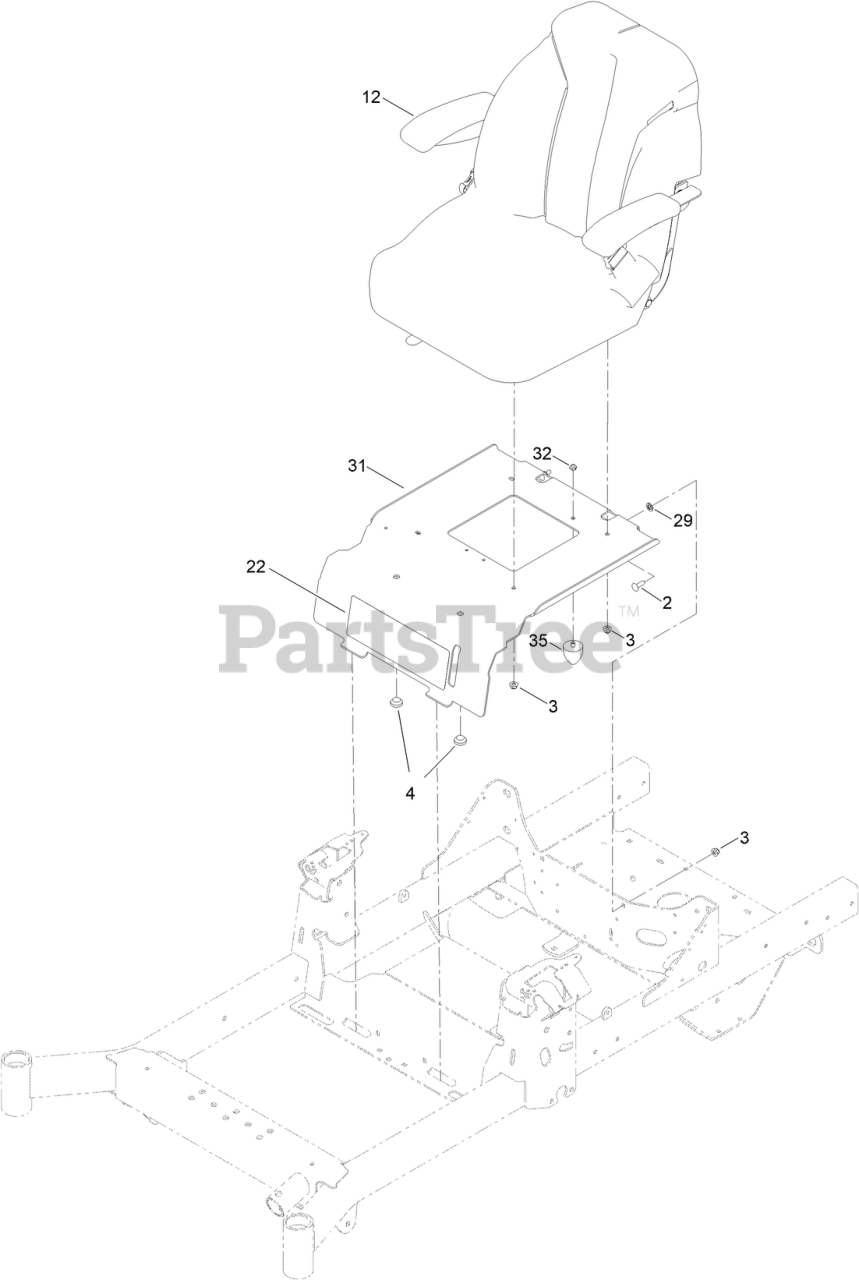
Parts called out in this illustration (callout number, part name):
2	SCREW-CARR
3	NUT-HF, NI
4	BUMPER-SEAT
12	ASM-SEAT TORO
22	DECAL-TITAN MAX
29	WASHER-RETAINING
31	PLATE-FIXED SEAT [BLACK]
32	NUT-LOCK, NI
35	BUMPER-RUBBER
